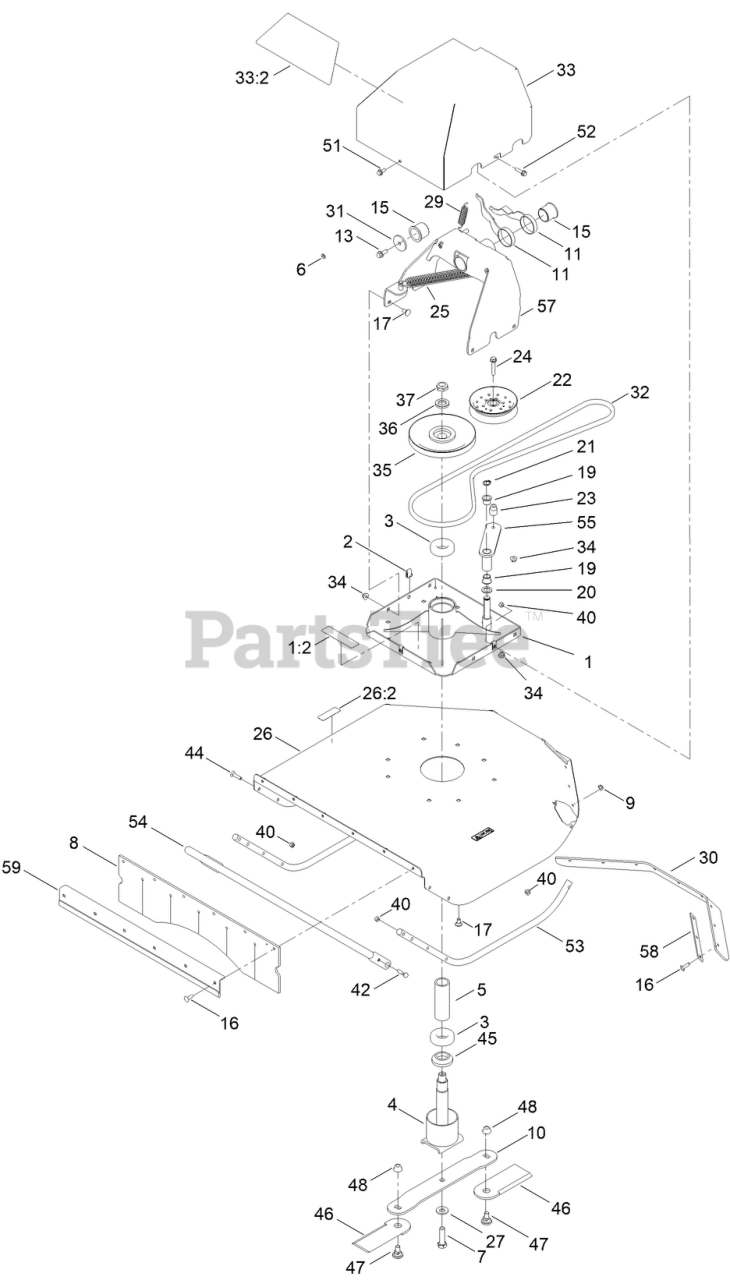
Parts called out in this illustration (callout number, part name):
1	SPINDLE ASM
1:2	DECAL-DANGER
2	NUT-U
3	BEARING-SPINDLE
4	SPINDLE CUP ASM
5	SPACER-BEARING
6	NUT-PUSH
7	SCREW-BLADE
8	FLAP-RUBBER
9	NUT-HF, NI
10	BLADE-FLAIL
11	ARM-RETURN
13	SCREW-HHF
15	BUSHING
16	SCREW-CARR
17	SCREW-CARR
19	BUSHING
20	WASHER
21	RING-RETAINING
23	BUSHING-IDLER
24	SCREW-HHF
25	Spring-Extension
26	DECK ASM
26:2	DECAL-WARNING, BLADE
27	WASHER-BELLEVILLE
29	SPRING
30	FLAP-DECK
31	WASHER-FLAT
32	BELT-DECK
33	GUARD-BELT
34	NUT-HF, NI
35	PULLEY-DRIVEN, LOW
36	WASHER-HARDENED
37	NUT-LOCK, NI
40	NUT-LOCK, NI
42	SCREW-HANDLE, LOCK
44	SCREW-CARR
45	CAP-SPINDLE
48	NUT-HHF
51	SCREW-HHF
52	SCREW-HHF
53	BAR-SKID
54	GUARD-BRUSH
55	ARM-TENSION
57	FRAME-PIVOT
58	PLATE-FLAP, DECK
59	GUARD-FLAP, RUBBER
